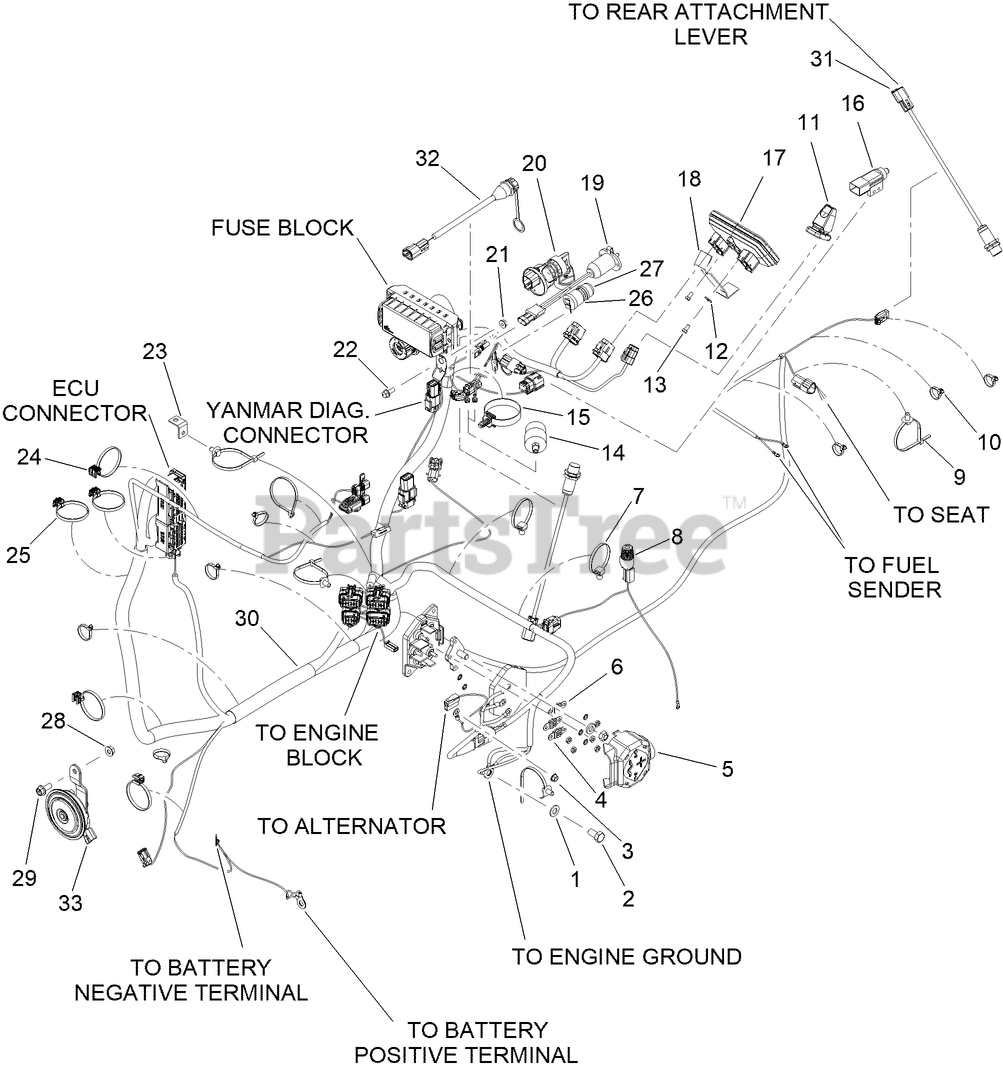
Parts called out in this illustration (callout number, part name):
1	WASHER-FLAT
2	SCREW-HH
3	NUT-HF
4	BK/AMI 60 AMP FUSE
5	MAIN FUSE HOLDER (3 BK/AMI FUSES)
6	BK/AMI 80 AMP FUSE
7	FIR TREE SMALL TIE
8	SWITCH-TEMP, 200 DEGREE
9	FIR TREE CABLE MOUNT
10	CABLE TIE (1/16" TO 4")
11	HPW SWITCH (FRICTION HOLD)
12	WASHER-PLAIN
13	SCREW-HH
14	SWITCH-PRESSURE, VACUUM
15	HEAVY DUTY FIR TREE (.04-.62 THK)
16	PLUNGER SWITCH
17	CCPILOT VI_2 3.5" DISPLAY
18	DISPLAY BRACKET
19	ACCESSORY SOCKET
20	IGNITION SWITCH ASM
21	NUT-HF
22	SCREW-HHF
23	BRACKET
24	EDGE CLIP SIDE VERTICAL (.12-.24)
25	EDGE CLIP SIDE HORIZONTAL (.12-.24)
26	BUTTON-HORN
27	COVER-BUTTON
28	NUT-HF
29	SCREW-HHF
30	HARNESS-MAIN
31	PROXIMITY SWITCH 18MM NPN N/O
32	USB DATA JUMPER W/CAP
33	HORN-HIGH FREQUENCY
